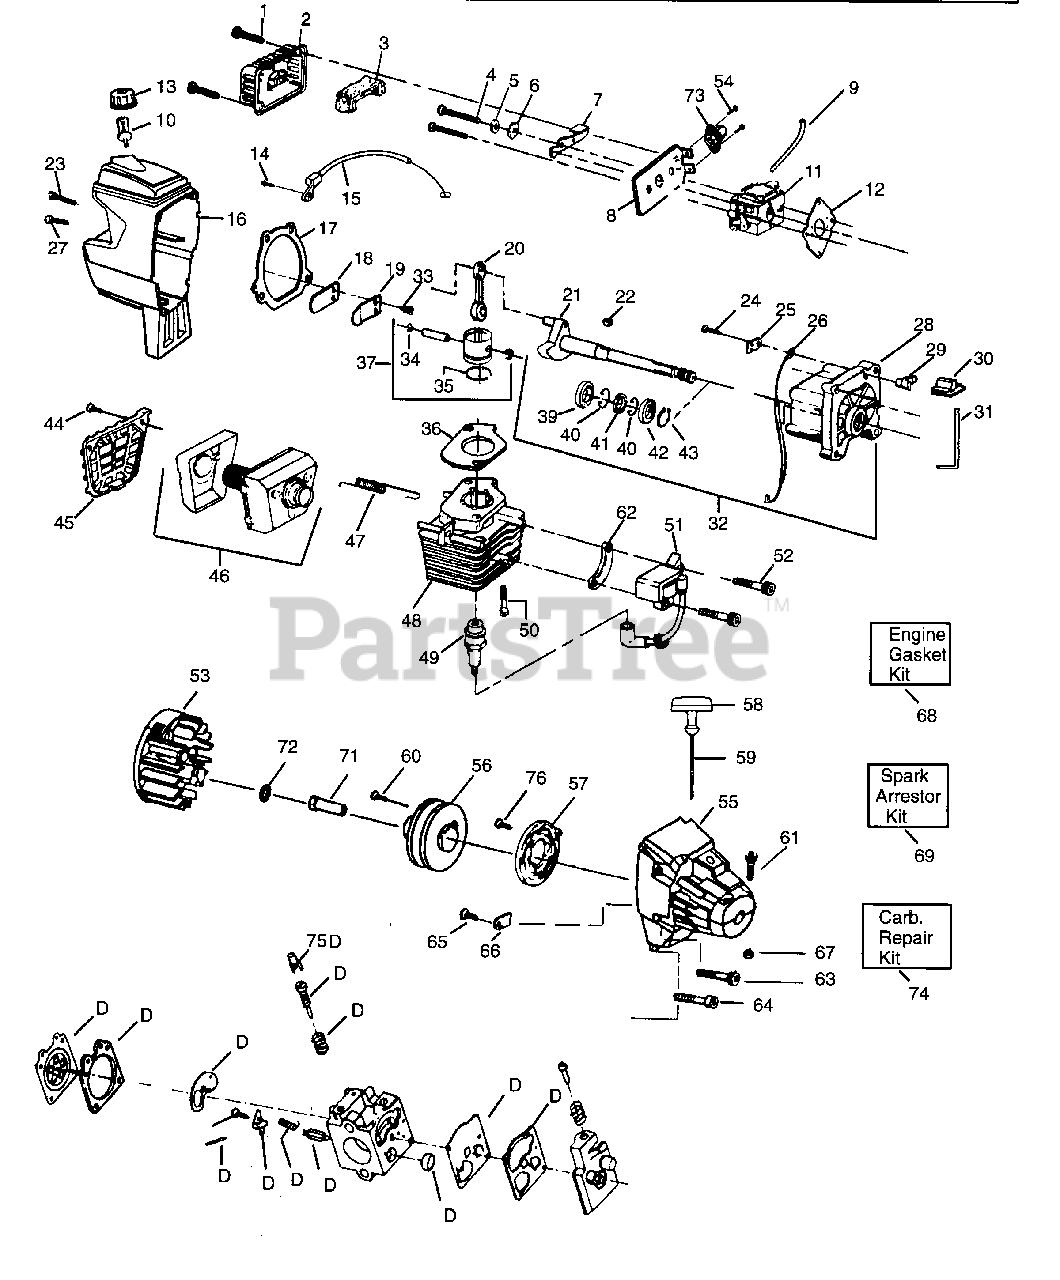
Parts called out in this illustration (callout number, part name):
1	Screw -Air Filter Cover
2	Air Filter Cover
3	Air Filter
4	Screw-Carburetor
5	Spacer-Choke
6	Wave Washer
7	Choke Shutter
8	Air Filter Plate
9	Fuel Line
10	Return Line
10	Fuel Pick-up Ass'y.
11	Carburetor (WA 219B) w/Limiter Cap
12	Carburetor Gasket
13	Fuel Cap Ass'y.
14	Screw-Throttle Cable
15	Throttle Cable Ass'y.
16	Shroud & Tank Ass'y.
17	Crankcase/Shroud Gasket
19	Reed Stop
20	Connecting Rod Ass'y. (Inc. Bearings)
21	Crankshaft Ass'y.
22	Flywheel Key
23	Screw-Shroud
24	Screw-Lead Wire
25	Switch Insulator
26	Lead Wire
27	Screw-Shroud
28	Crankcase Ass'y. (Inc. 39-42)
29	Switch Ramp
30	Cover-Kill Switch
31	Switch Spring
32	Crankcase & Crankshaft Ass'y (Inc. 21, 28, & 39-43)
33	Screw-Reed
34	Piston Pin Retainer
35	Piston Ring
36	Cylinder Gasket
37	Piston Kit (Inc. 34,35 & pin)
39	Inner Bearing
40	Retaining Ring
41	Crankshaft Seal
42	Outer Bearing
43	Crankshaft Retaining Ring
44	Screw-Muffler Guard
45	Muffler Guard
46	Muffler Kit
47	Muffler Attachment Spring
48	Cylinder
49	Spark Plug (RCJ-8Y)
50	Screw-Cylinder
51	Ignition Module Kit
52	Screw
53	Flywheel Ass'y.
54	Screw-Primer Bulb
55	Fan Housing
56	Starter Pulley (INC. 60)
57	Starter Spring
58	Starter Handle
59	Rope Kit
60	Screw-Rope Retaining
61	Screw-Pinch Camp
63	Screw-Fan Housing
64	Screw-Fan Housing
65	Screw-Retainer
66	Retainer
67	Locknut-Pinch Clamp
68	Engine Gasket Kit
69	Spark Arrestor Kit
71	Drive Coupling
73	Primer Bulb Ass'y.
74	Carburetor Repair Kit
75	Limiter Cap
76	Screw-Starter Spring
